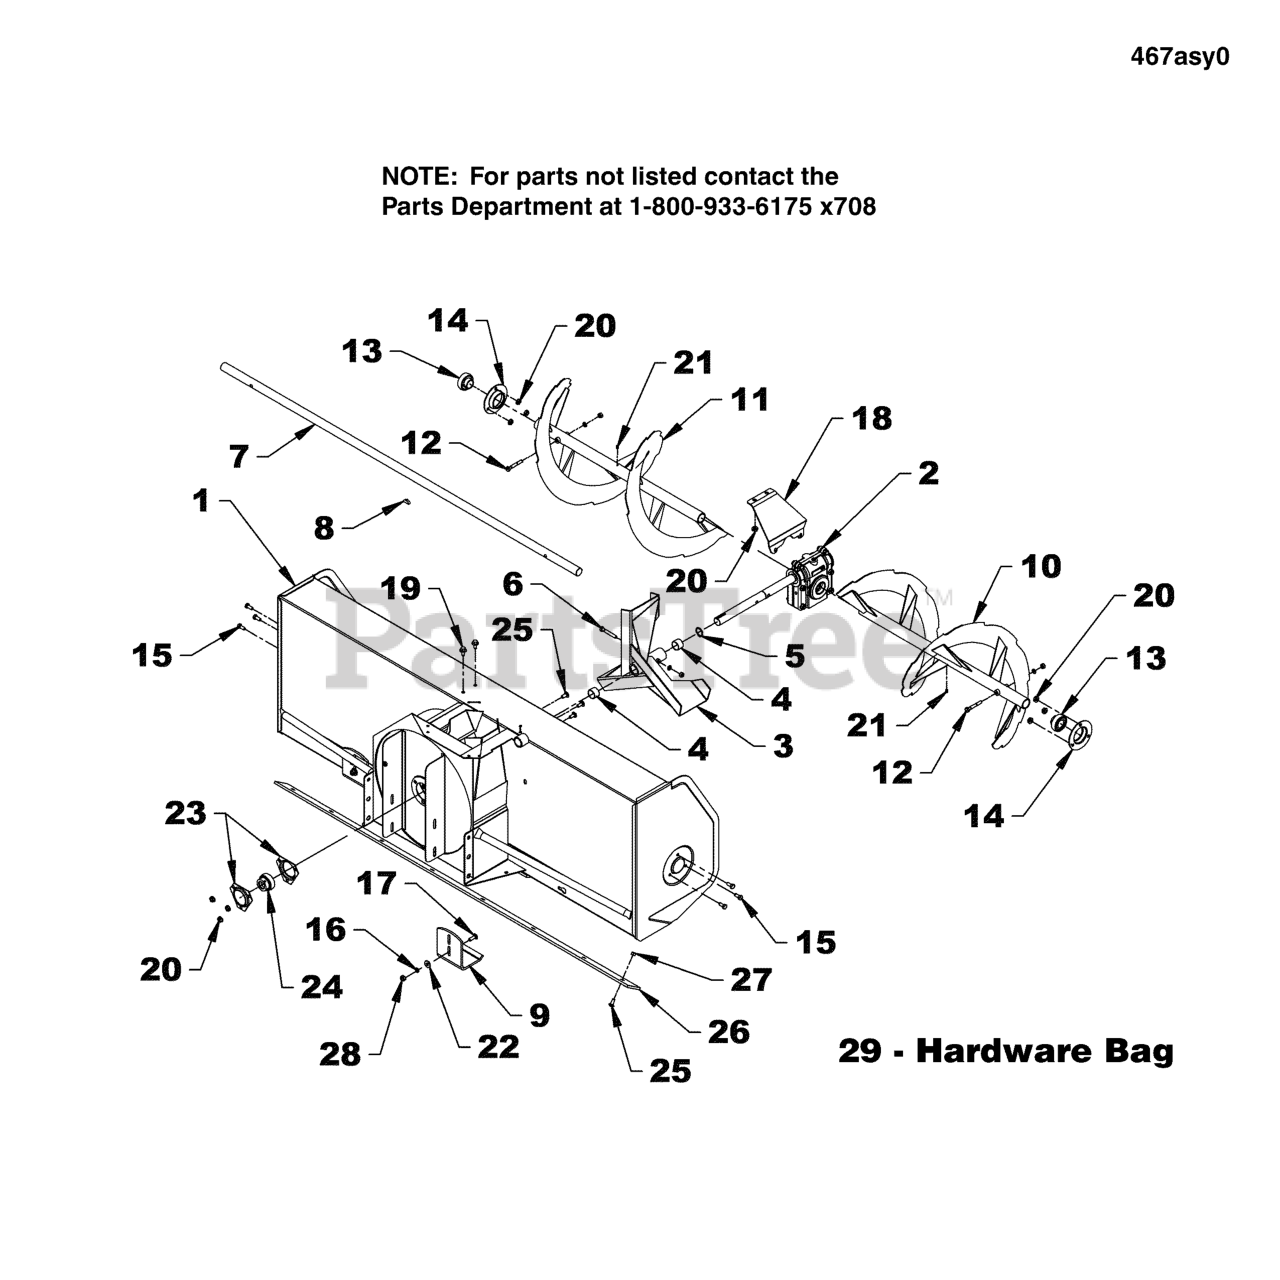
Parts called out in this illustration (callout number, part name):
1	Housing
2	Gearbox ass'y (ccw)
3	Fan including bushings 4300055
4	Bushing (iolite)
5	Outer retaining ring
6	Shear bolt 5/16" NC x 2 1/4" w/ lock & nut, gold PTD, gr8
7	Output shaft
8	Woodruff key
9	Skid shoe
10	Auger - RH
11	Auger - LH
12	Shear bolt 5/16" NC x 2 1/4" w/ lock & nut, silver PTD, gr5
13	Bearing with locking collar
14	Flange
15	Hex. bolt 5/16" NC x 3/4" gr.5 PTD
16	Lockwasher 5/16" PTD
17	Carriage bolt 5/16" x 1" gr.5 PTD
18	Gearbox support
19	Serrated flange bolt 5/16" NC x 3/4" lg, PTD
20	Serrated flange nut 5/16" NC, PTD
21	Grease fitting
22	Flat washer 5/16" (Æ3/8" int.) PTD
23	Flange
24	Bearing with locking collar
25	Carriage bolt 5/16" NC x 3/4" gr.5 PTD
26	Cutting edge
27	Stover nut 5/16" NC PTD
28	Nylon insert nut 5/16" NC, PTD
